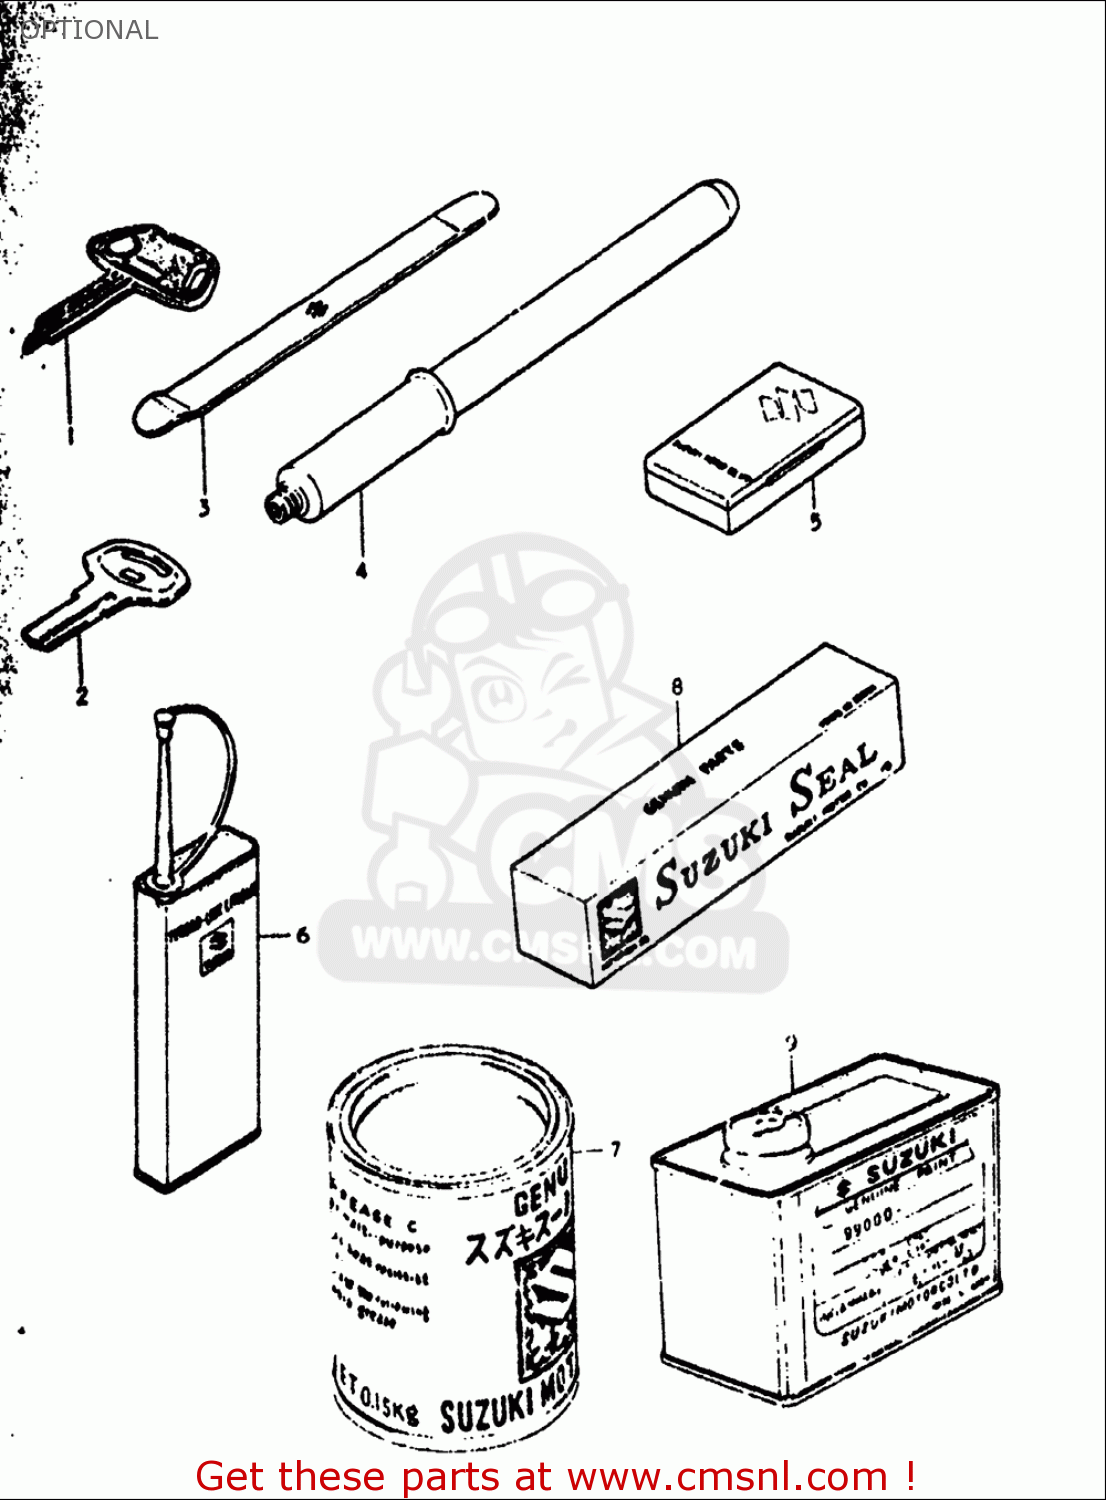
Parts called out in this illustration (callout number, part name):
2	KEY,BLANK
3	LEVER,TIRE
6	THREAD LOCK NO.1401 CLEAR 200G
7	GREASE(C)EP2 LITHIUM 150G
